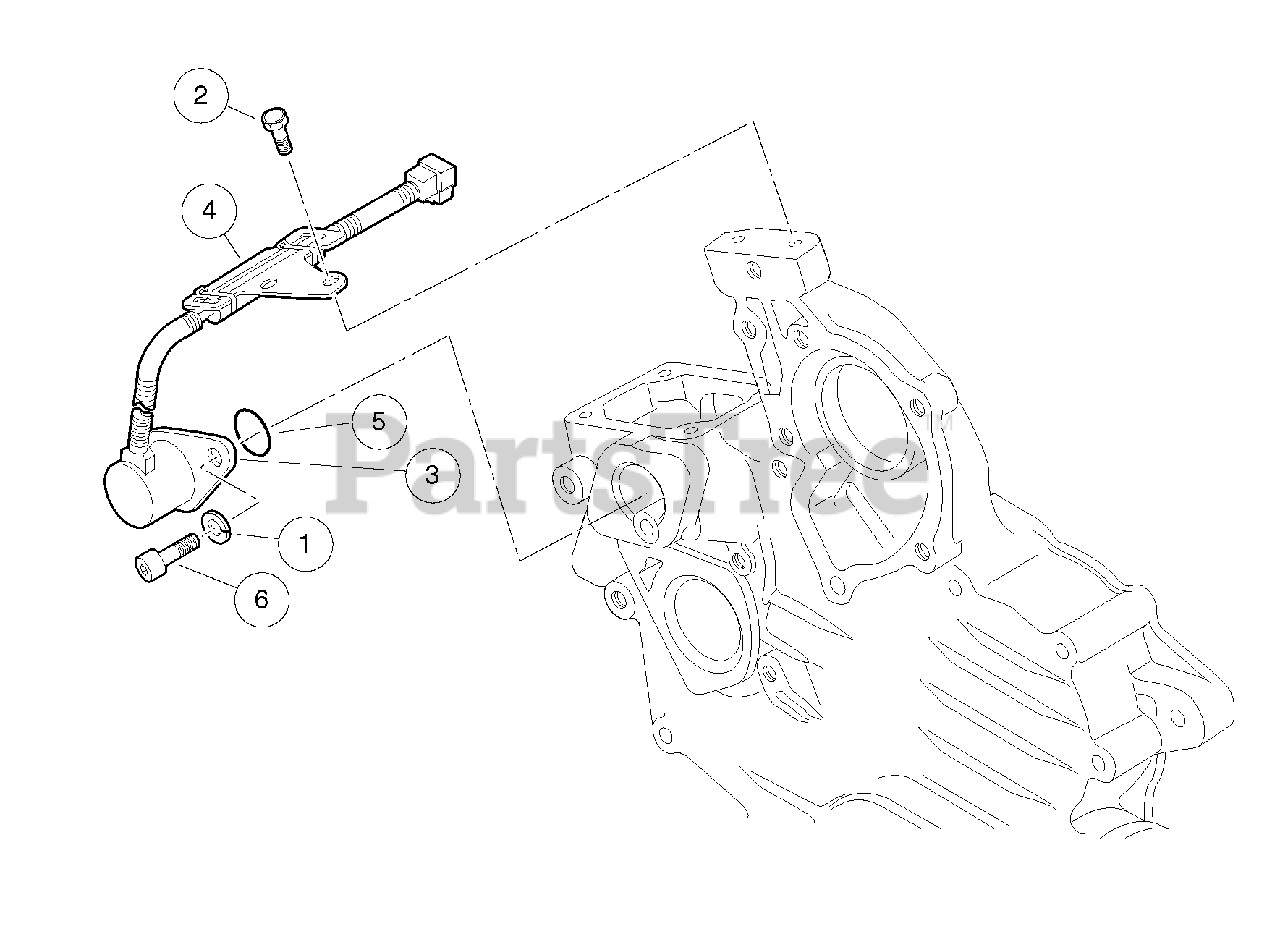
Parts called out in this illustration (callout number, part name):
1	Washer, Spring, M6, D722
2	Bolt, Solenoid, Stop, D722
3	Solenoid, Stop
4	Stay, Stop Solenoid
5	O-Ring, Stop Solenoid
6	Bolt, Stop Solenoid
